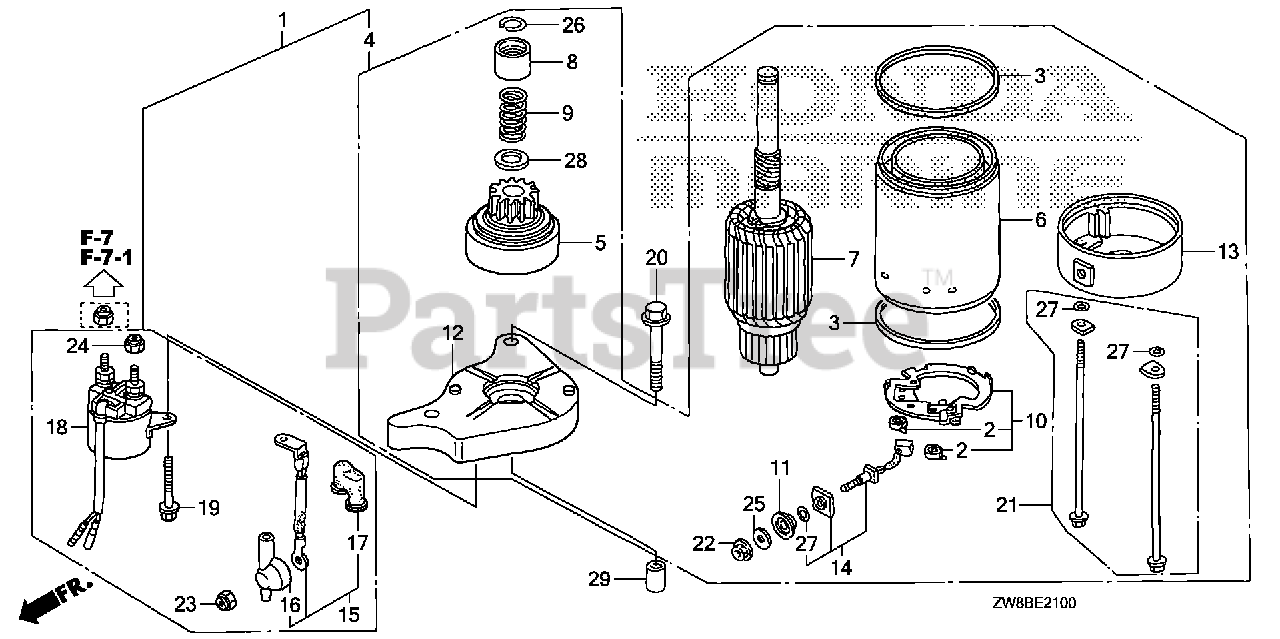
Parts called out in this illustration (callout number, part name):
1	MOTOR ASSY., STARTER
2	SPRING, CARBON BRUSH
4	MOTOR UNIT, STARTER
8	PIECE, STOPPER
9	SPRING, RETURN
10	HOLDER, BRUSH
12	BRACKET, FR.
13	BRACKET, RR.
14	UNIT, TERMINAL
15	WIRE, MAGNETIC SWITCH
16	COVER, STARTER TERMINAL
17	COVER, MAGNETIC SWITCH TERMINAL
18	SWITCH ASSY., STARTER MAGNETIC
19	BOLT, FLANGE (6X14)
20	BOLT, FLANGE (8X45)
21	BOLT, SETTING
22	NUT-WASHER (6MM)
23	NUT, LOCK (6MM)
24	NUT, LOCK (6MM)
25	WASHER (6MM)
26	CIRCLIP (14MM)
27	O-RING
29	PIN, DOWEL (10X12)
